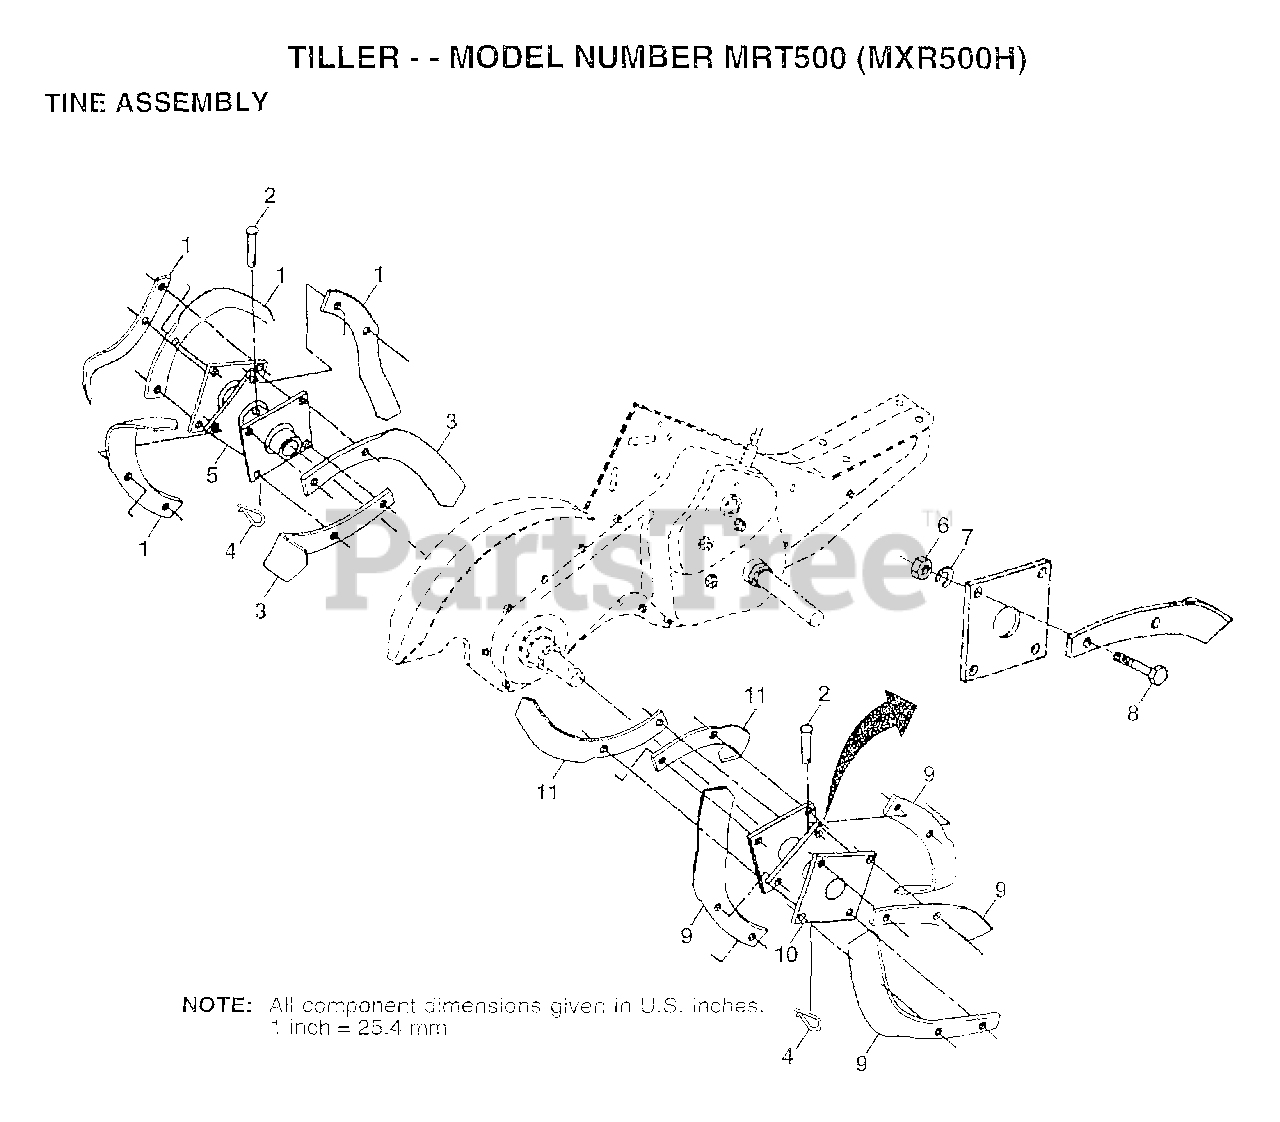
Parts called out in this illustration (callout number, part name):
2	PIN.CLEVIS.SHEAR
3	"TINE.LH.12"""
4	RETAINER.SPRING
5	HUB&PLATE ASM LH
7	LOCKWASHER
8	BOLT
10	HUB&PLATE ASM RH
11	"TINE.RH.12"""
